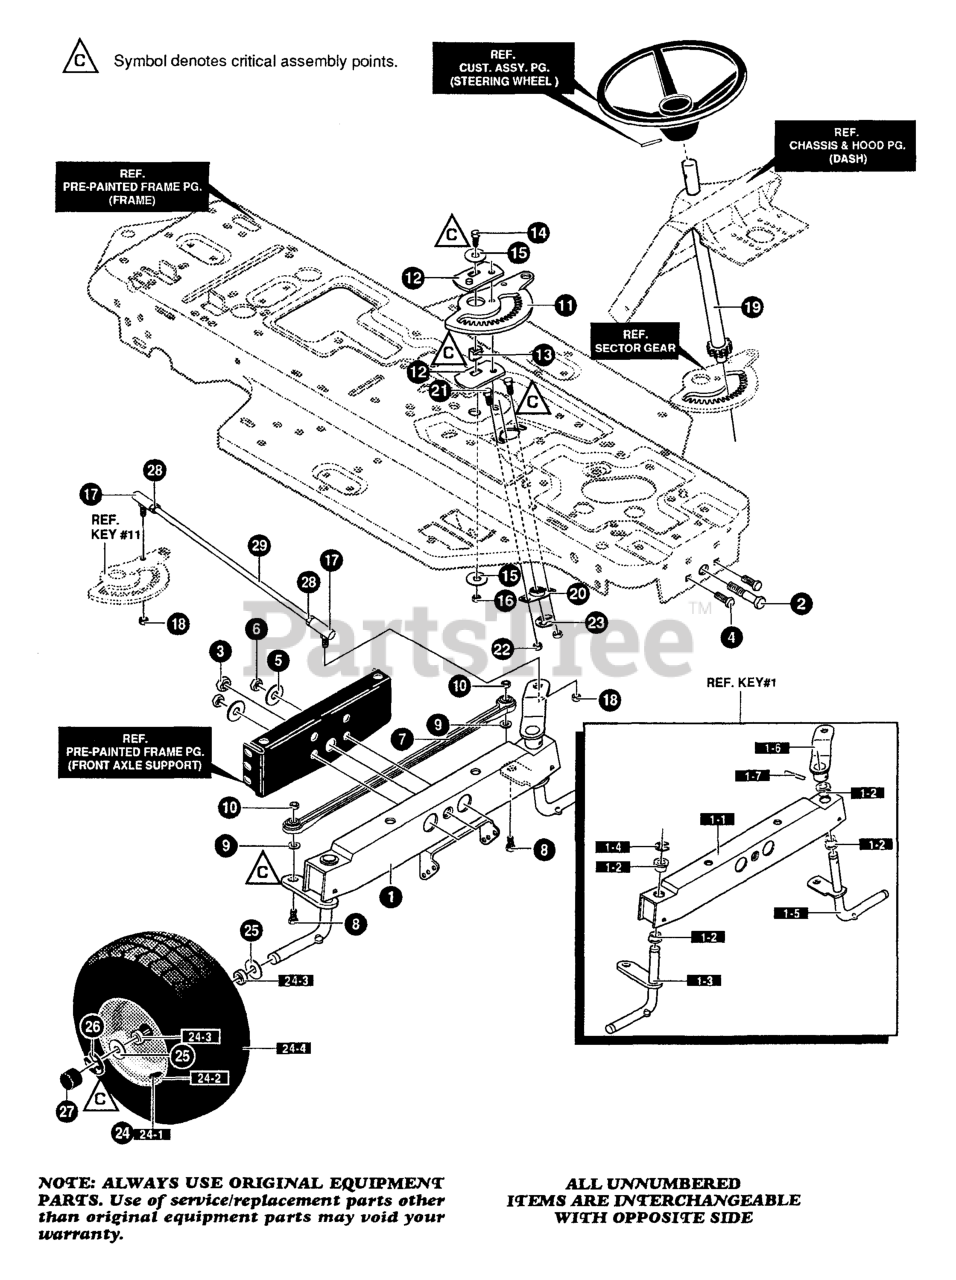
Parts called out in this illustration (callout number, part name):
1	AXLE FRONT ASSEMBLY
1-1	ASSEMBLY, FRONT AXLE
1-2	BEARING, FLANGE
1-3	SPINDLE, ASSEMBLY, RH
1-4	RING, RETEX
1-5	SPINDLE, ASSEMBLY, LH
1-6	ARM ASSEMBLY
1-7	PIN, SPRING
2	BOLT, .625 X 1.890
3	NUT, 1/2-20
4	SCREW, 3/8-16 x 3.00
5	WASHER, .391D X 1.25D X .07
6	NUT, 3/8-16
7	TIE ROD, 19.31
8	SCREW, 3/8-16 X 1.25
9	WASHER, .393 X .68 X .10
10	NUT, 3/8-16
11	GEAR, SECTOR
12	PLATE SECTOR
13	BUSHING, SECTOR
14	SCREW, 3/8-24 X 1.50
15	WASHER, FLAT .390 X 1.25 X .119
16	NUT, 3/8-24
17	BALL JOINT 3/8
18	NUT, 3/8-24
19	SHAFT, PIN-STEER
20	BEARING, FLANGE
21	SCREW, 1/4-2020.75
22	NUT, 114-20
23	RING, RET E
24	TIRE 6: RIM ASSEMBLY, 15 X 6.-6
24-1	VALVE STEM
24-2	RIM, WHEEL
24-3	BEARING
24-4	TIRE, 15 X 6-6
25	WASHER, FLAT .755 X 1.31 X .075
26	RING, RETEX
27	HUB CAP
28	NUT, 3/8-24
29	DRAG LINK
